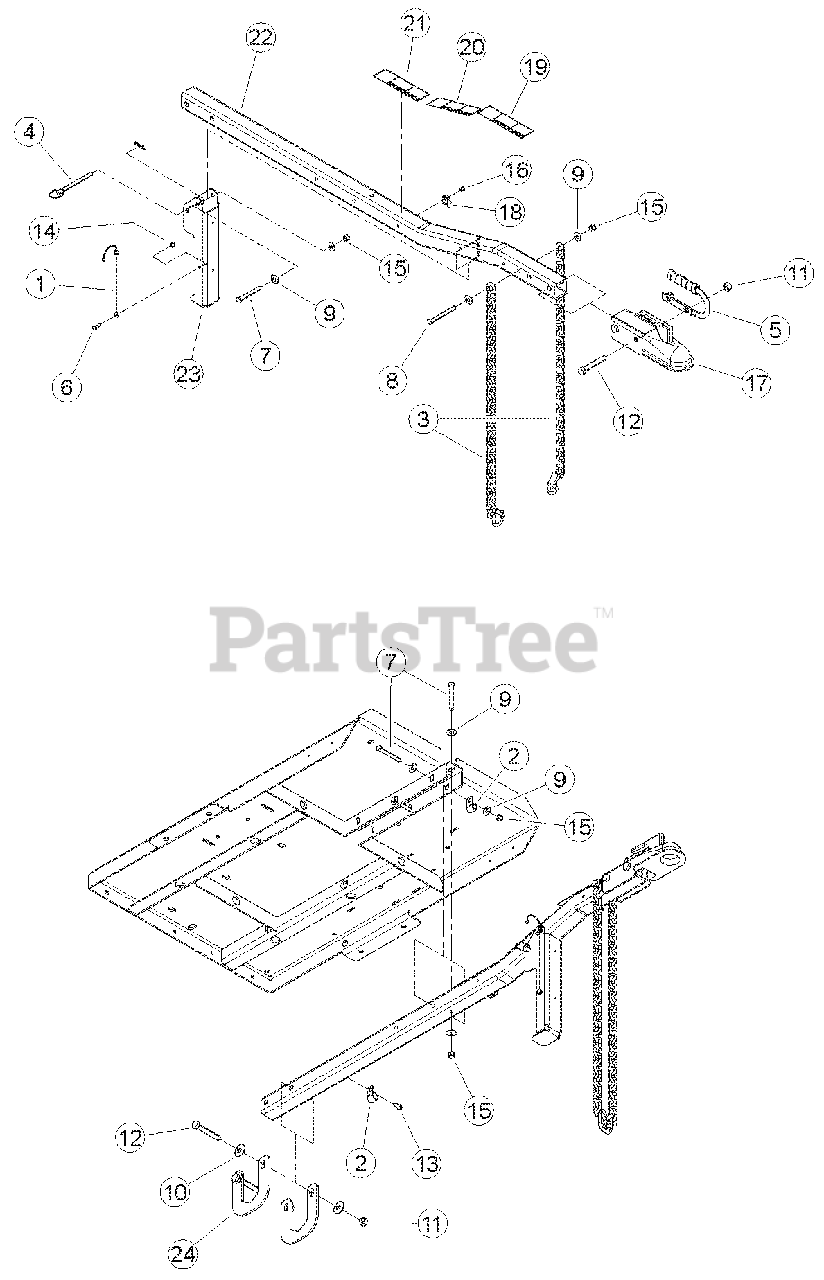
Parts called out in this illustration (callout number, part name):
1	LANYARD, NYLON
2	CLAMP, 9/16" COATED
3	CHAIN, SAFETY 5000 LB W/LATCH
4	PIN, 3/8 HITCH
5	HANDLE, HITCH COUPLER
6	BOLT, 1/4 X 3/4 HEX HD GR5 ZP
7	BOLT, 3/8 X 3 HEX HD GR5 ZP
8	BOLT, 3/8 X 3-1/2 HEX HD GR5 ZP
9	WASHER, 3/8 FLAT ZP
10	WASHER, 1/2 FLAT ZP
11	NUT, 1/2 CENTERLOCK GRB ZP
12	BOLT, 1/2 X 3-1/4 HEX HD GR5 ZP
13	NUT, 1/4 NE NYLOCK ZP
14	NUT, 3/8 NE NYLOCK ZP
15	BOLT, 3/8 X 3-1/4 HEX HD GR5 ZP
16	DECAL, HITCH LOAD
17	TRAILER HITCH COUPLER
18	POLE, C/S HITCH
19	STAND, JACK
20	PLATE, HITCH
